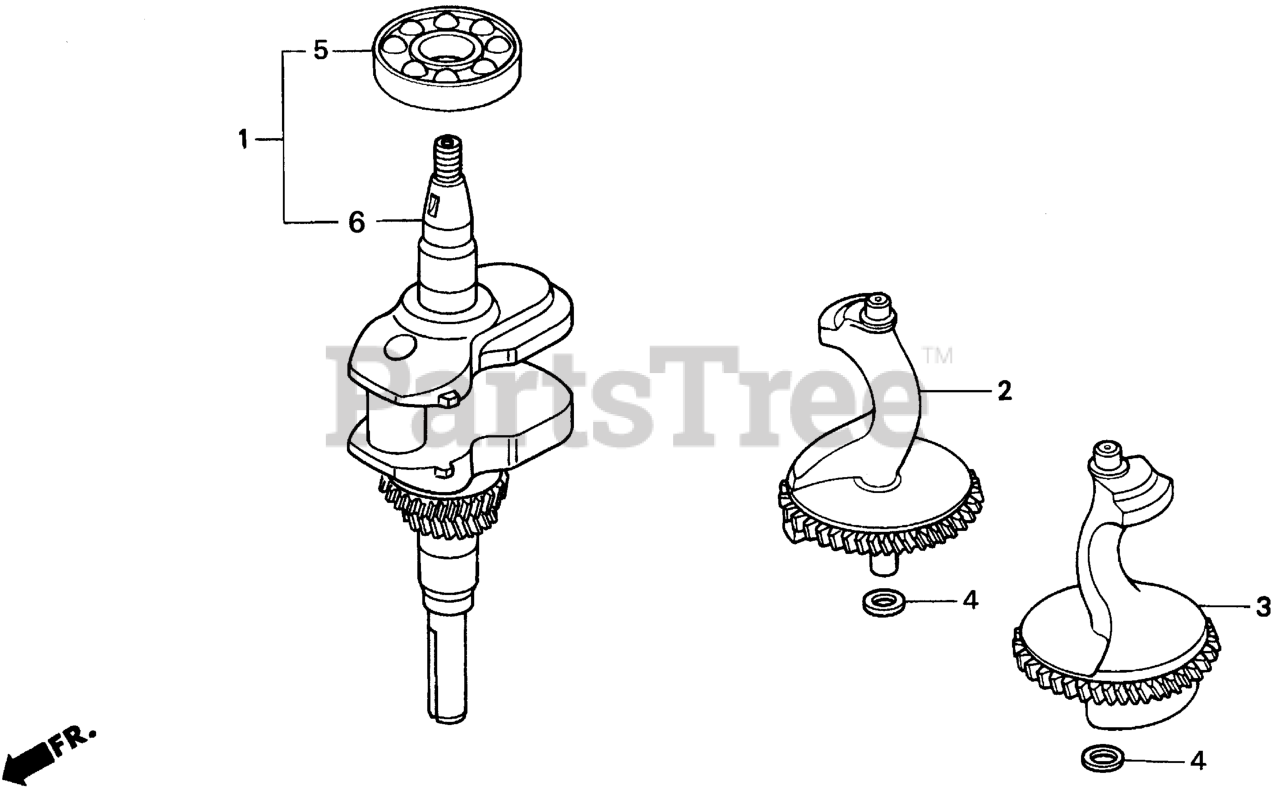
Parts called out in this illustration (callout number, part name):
2	WEIGHT A, BALANCER
3	WEIGHT B, BALANCER
4	WASHER, THRUST (14MM)
6	CRANKSHAFT
